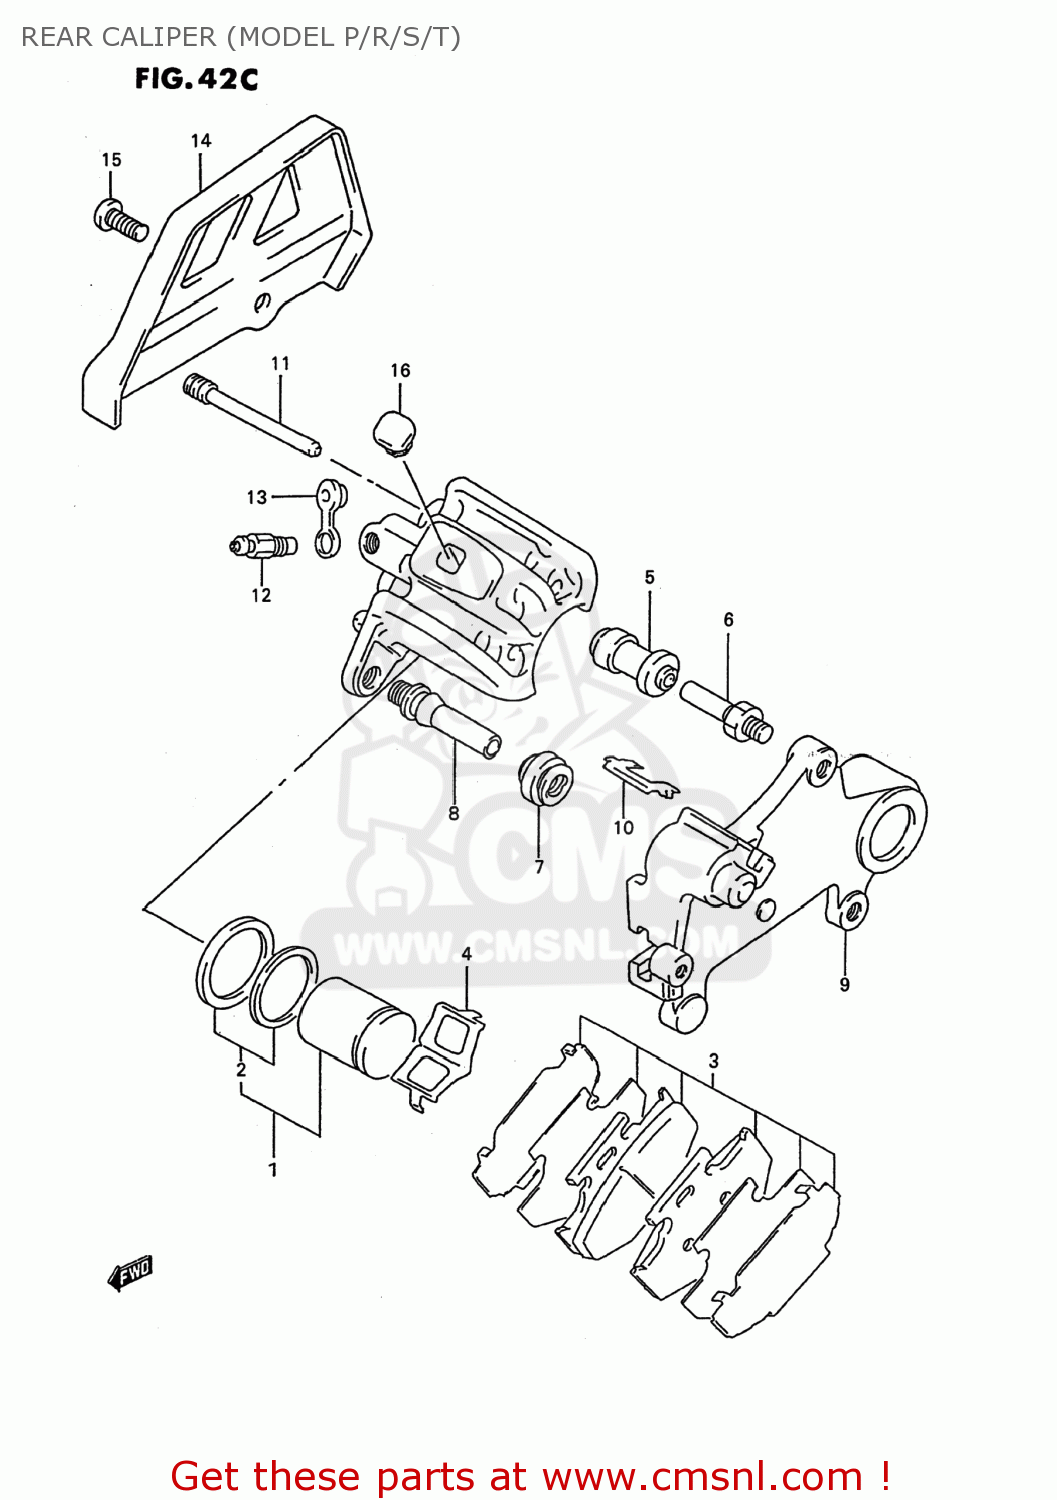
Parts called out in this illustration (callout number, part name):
1	PISTON SET
2	SEAL SET,PISTON
3	PAD & SHIM SET (NAS)
4	SPRING,PAD
5	BOOT
6	PIN,BOLT
7	BOOT
8	PIN
9	BRACKET
10	RETAINER,BRACKET
11	PIN,HANGER
12	BLEEDER
13	CAP,BLEEDER
14	GUARD SET,REAR CALIPER
15	SCREW 6X12
16	COVER,RR CALIPER BODY
